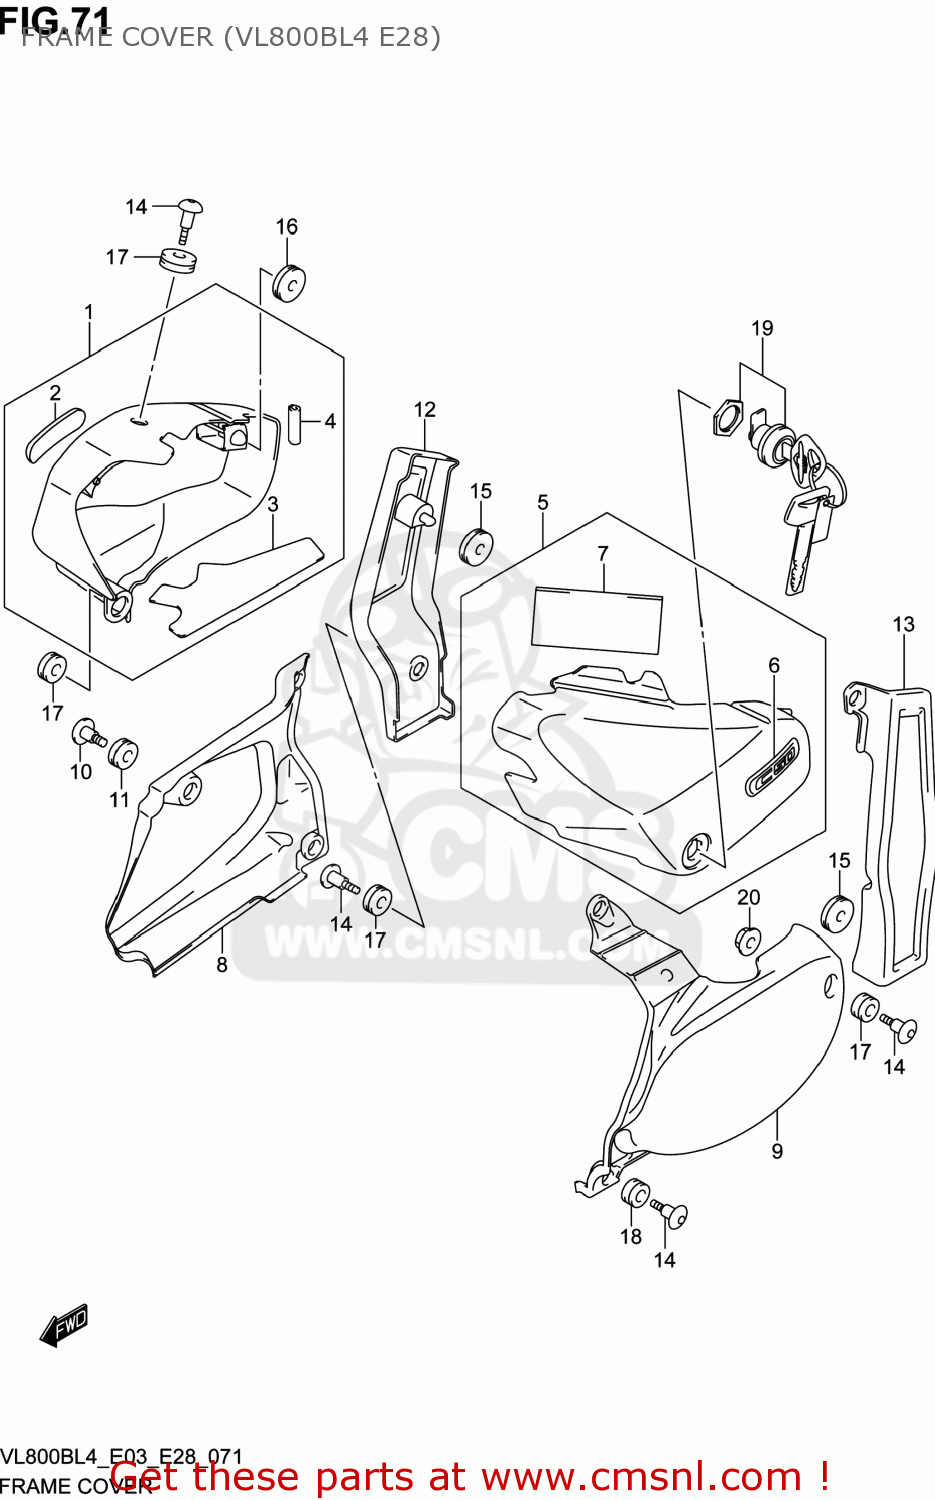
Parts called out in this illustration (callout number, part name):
1	COVER,SIDE,R
2	EMBLEM,C50
3	SHIELD,FRAME COVER
4	MOLDING
5	COVER,SIDE,L(BLACK)
6	EMBLEM,C50
7	CUSHION,LUGGAGE BOX
8	COVER,SIDE LWR,R
9	COVER,SIDE LWR,L
10	SCREW,SIDE COVER LWR,R
11	CUSHION
12	COVER,SIDE RR,R
13	COVER,SIDE RR,L
14	SCREW(6X20)
15	CUSHION
16	CUSHION
17	CUSHION
18	CUSHION
19	LOCK SET,COVER
20	NUT
